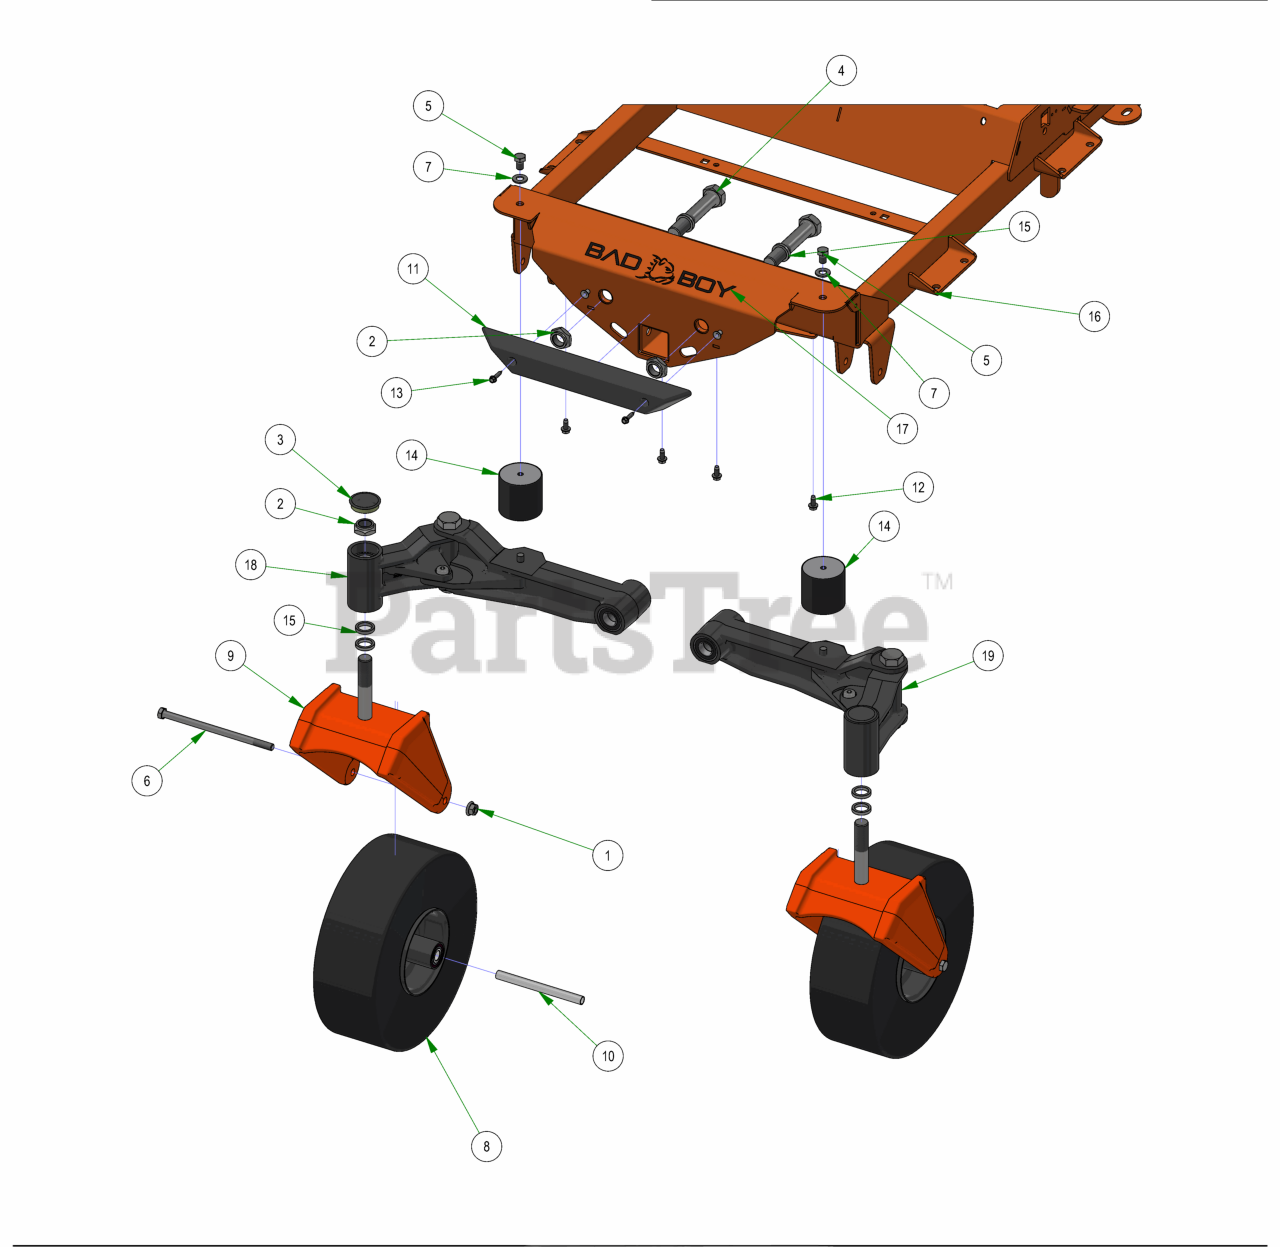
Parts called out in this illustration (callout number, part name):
1	1/2-13 NYLON INSERT FLANGE LOCKNUT ZINC
2	1"-14 NYLON INSERT JAM LOCKNUT ZINC
3	2017 Bearing Cover
4	1"-14 X 5-1/2 HEX CAP SCREW (GR.8) ZINC YELLOW
5	1/2-13 X 3/4 HEX CAP SCREW (GR.5) ZINC
6	1/2-13 X 9 HEX CAP SCREW (GR.5) ZINC
7	1/2 SAE FLAT WASHER (1-1/16" OD) GR.8 ZINC YELLOW
8	2019 15x6.00-6 Non Pneumatic Black Front Assembly
9	2020 R Series Cast Front Fork
10	Front Wheel Spanner
11	2017 XP BUMPER
12	5/16-18 X 3/4 HEX WASHER SLOT (F) TCS ZINC
13	1/4-14 X 1-1/4 HEX WASHER UNSLOT TEK/3 ZINC
14	Vibration Mount-Blue Dot
15	1.02 ID X 1.38 OD X .250 THK SPACER ZINC
16	2022 Horizontal Diesel Frame
17	Flying Bulldog Front Bumper Decal
18	2022 61/72 Rogue/Renegade Front Suspension Asy RH
19	2022 61/72 Rogue/Renegade Front Suspension Asy LH
